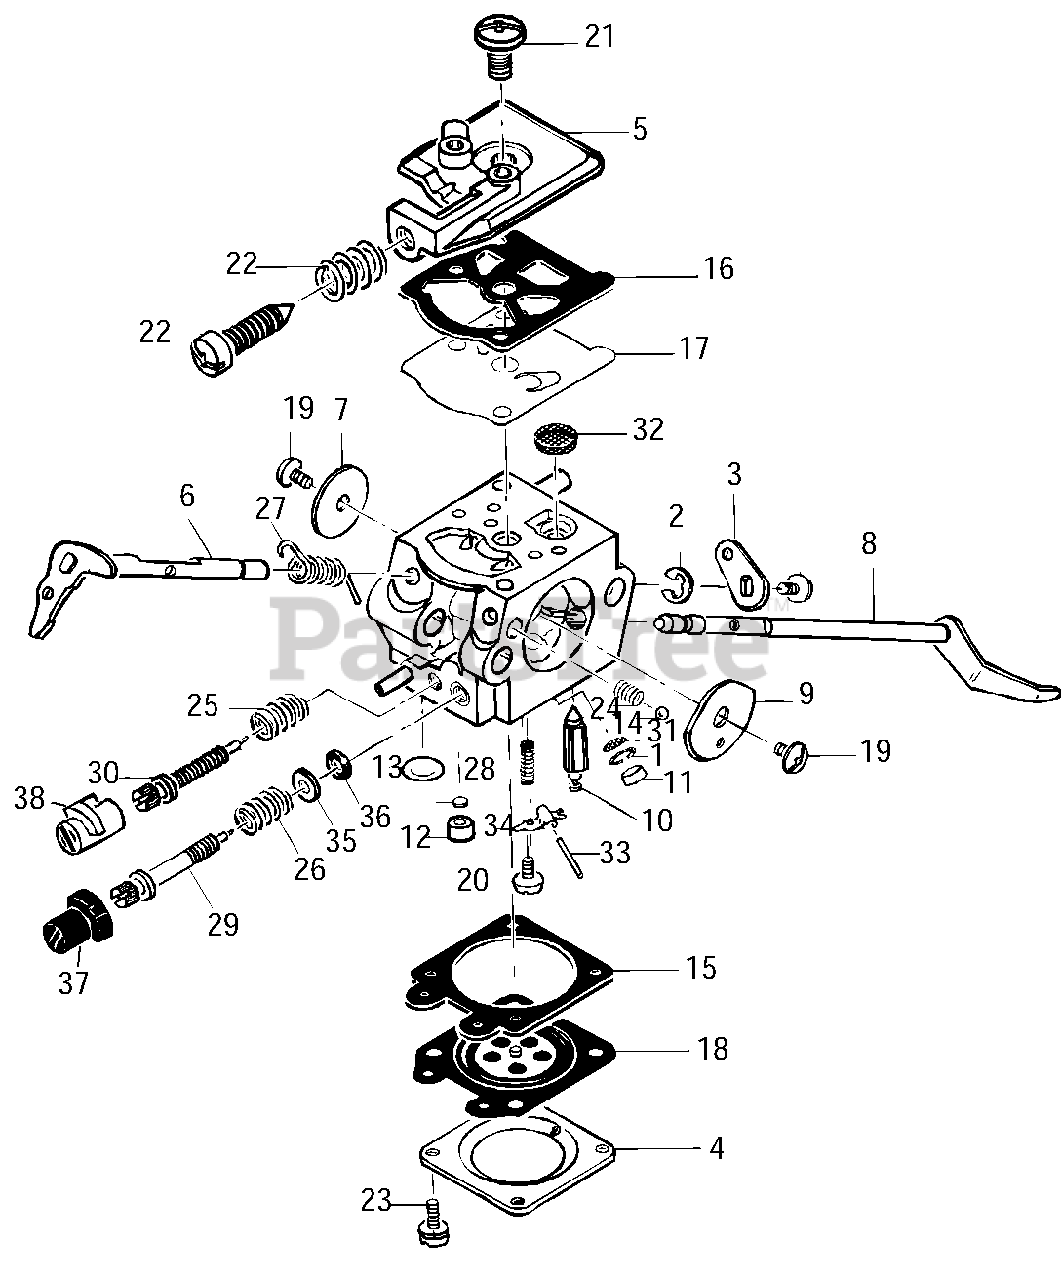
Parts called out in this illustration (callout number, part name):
1	Ring, Screen Retainer
2	Ring, Shaft Retainer
3	Lever, Throttle
4	Cover, Metering Lever
5	Cover, Fuel Pump
6	Shaft Asy, Throttle
7	Valve, Throttle
8	Shaft Asy, Choke
9	Valve, Choke
10	Valve, Inlet Needle
11	Seat Asy, Check Valve
12	Plug, Cup
13	Plug, Welch
14	Ball, Choke Friction
15	Gasket, Metering Diaphragm
16	Gasket, Fuel Pump
17	Diaphragm, Fuel Pump
18	Diaphragm Asy, Metering
19	Screw, Valve
20	Screw, Metering Lever Pin
21	Screw, Pump Cover
22	Spring, Idle Adjust Kit
23	Screw, Metering Cover
24	Spring, Choke Friction
25	Spring, Idle Needle
26	Spring, High Speed Needle
27	Spring, Throttle Return
28	Spring, Metering Lever
29	Needle, High Speed
30	Needle, Low Speed
31	Screen, Check Valve
32	Screen, Fuel Inlet
33	Pin, Metering Lever
34	Lever, Metering
35	Ring, High Speed
36	Washer, High Speed
37	Cap, Limiter, High, Black
38	Cap, Limiter, Low, White
